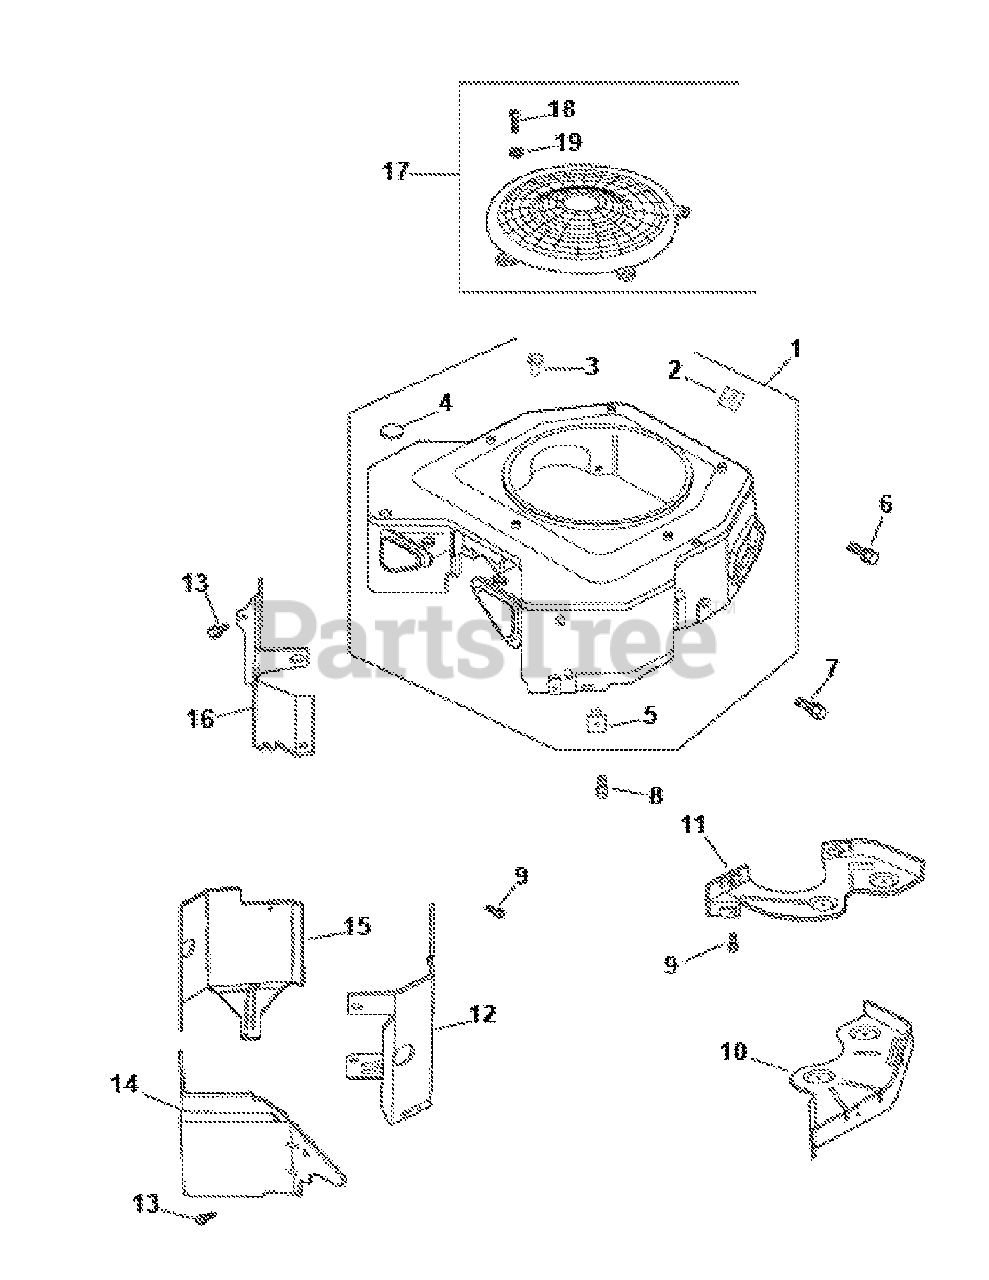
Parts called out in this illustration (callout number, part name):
1	Blower Housing
3	Tapping Screw
4	9/16" Button Plug
6	Screw
8	Screw
10	Backing Plate # 2
11	Backing Plate # 1
12	Cylinder Barrel Baffle # 2 Side
14	Valley Baffle # 2 Side
15	Cylinder Barrel Baffle # 1 Side
16	Valley Baffle # 1 Side
17	Fixed Guard Kit
18	Pan Head Screw
